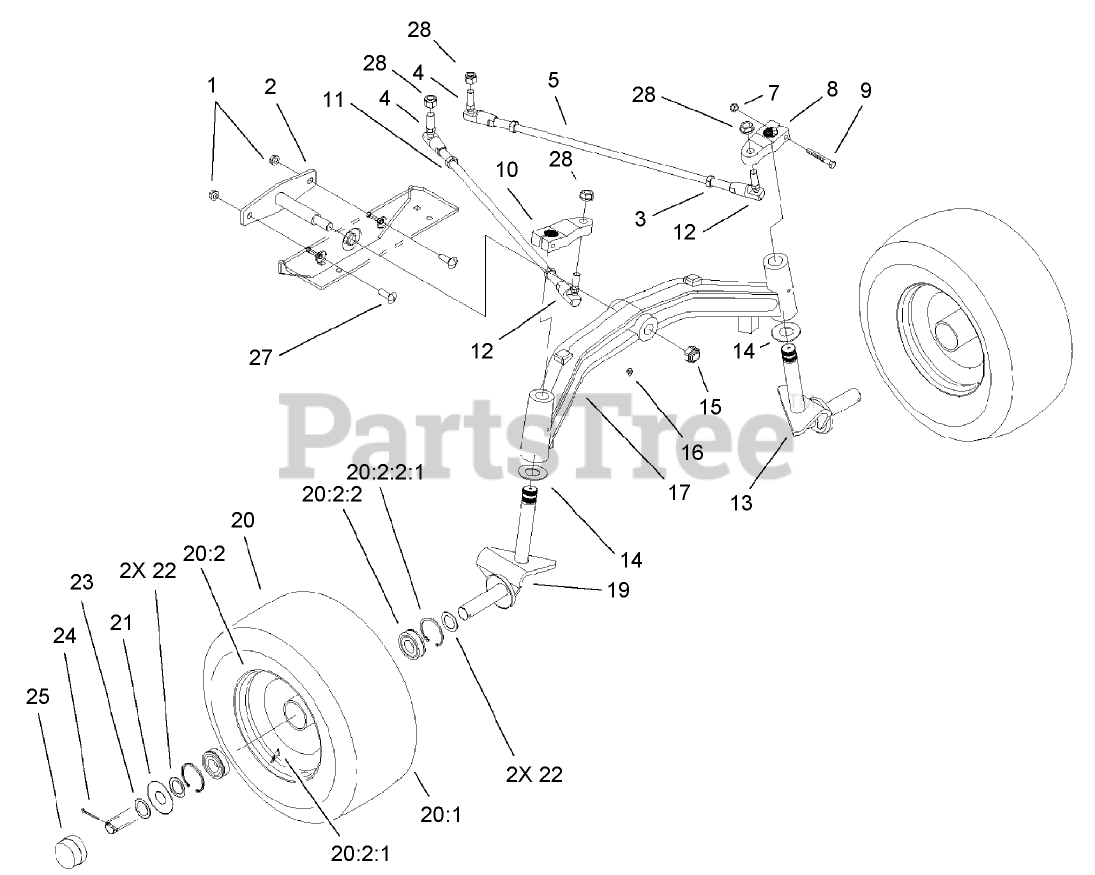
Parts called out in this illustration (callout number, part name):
1	NUT-LOCK, NI
3	NUT-JAM
4	BALLJOINT-THREAD, LH
5	ROD-TIE
7	NUT-LOCK, NI
8	ARM-STEERING, LH
9	SCREW-HH
10	ARM-STEERING, RH
11	NUT-HEX JAM LH
12	BALLJOINT-THREAD, RH
13	SPINDLE-LH
14	WASHER-THRUST
15	NUT-LOCK
16	FITTING-GREASE
17	AXLE-FRONT
20	WHEEL AND TIRE ASM
20:2	RIM ASM
20:2:1	VALVE
20:2:2	BEARING
21	WASHER-WHEEL
23	WASHER
24	PIN-COTTER
25	CAP-DUST
27	BOLT-CARR
28	NUT-LOCK
